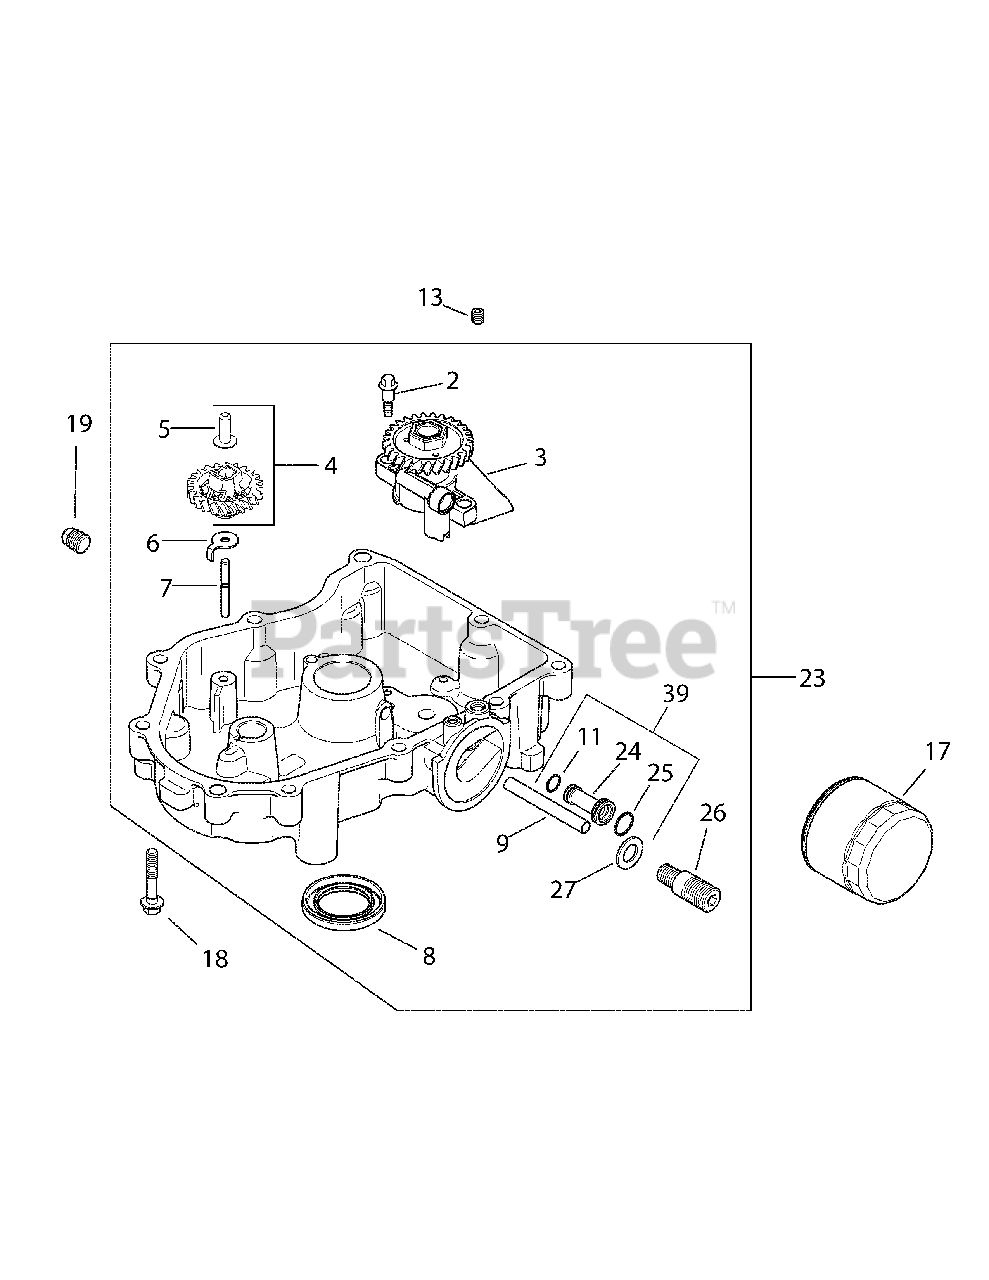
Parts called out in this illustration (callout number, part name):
2	Shd. Thd. Frm. Screw, M6 X .0 X 6.5
3	Oil Pump Assembly
4	Governor Gear w/ Pin Kit (Inc. 5)
5	Governor Regulating Pin
7	Governor Gear Shaft
9	Oil Feed Tube - Filter To Pan
11	Oil Pick-Up O-Ring
13	Plug, Ctsk. Pipe Plug, 1/8
18	Flg. Screw, M8 x 1.25 x 45
19	Sq. Hd. Pipe Plug, 3/8
23	Oil Pan Assembly (Inc. 2-9, 11, 24-27)
24	Oil Feed Tube
26	Oil Filter Nipple
39	Oil Feed Tube Assembly
